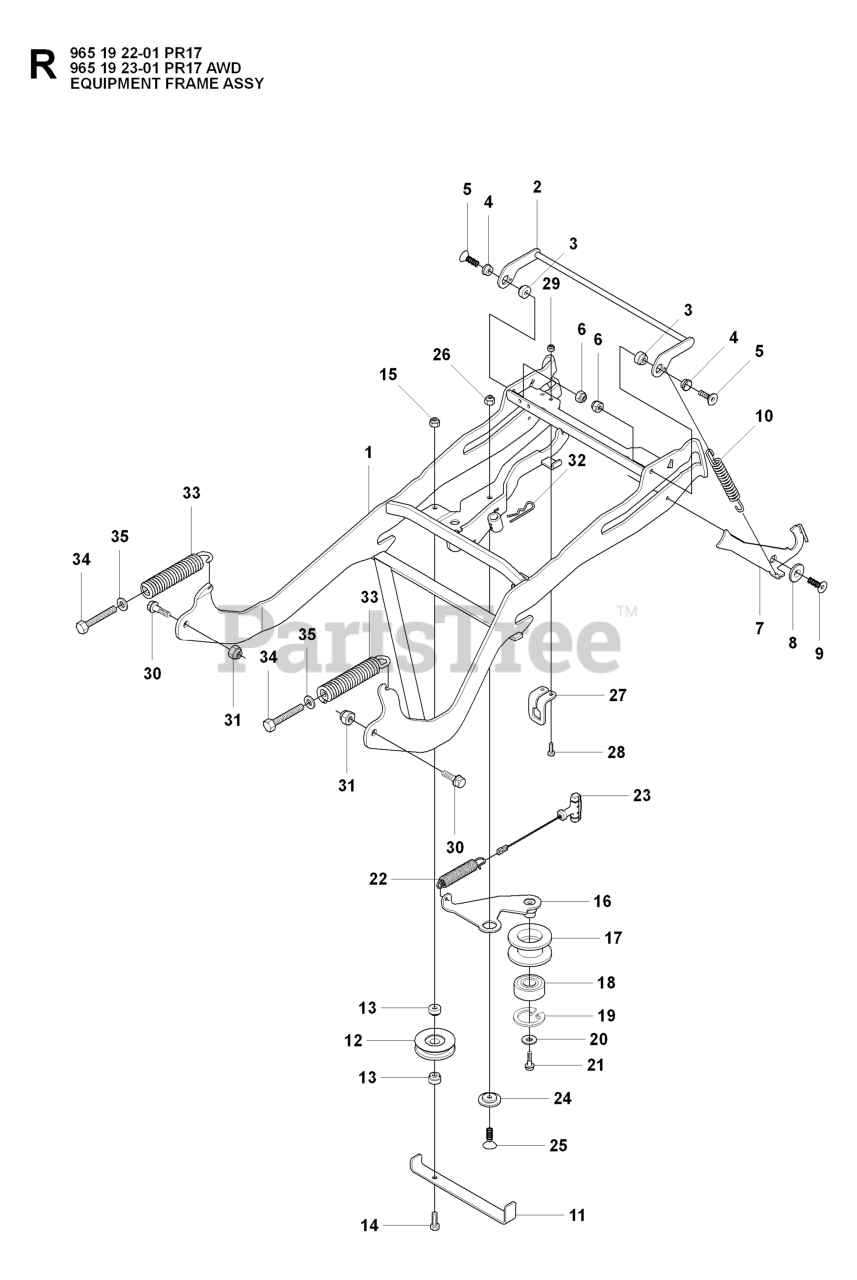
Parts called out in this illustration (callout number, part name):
6	LOCKNUT M8
8	SPACER
9	BOLT REAR WHEEL
12	PULLEY ASSY
14	SCREW
15	LOCKNUT M8
17	%PULLEY
18	BALL BEARING 6004-2RS1
19	RETAINING RING
24	WASHER
26	LOCKNUT M8
28	BOLT FLANGE - M6X20
29	LOCKNUT M6
35	WASHER
